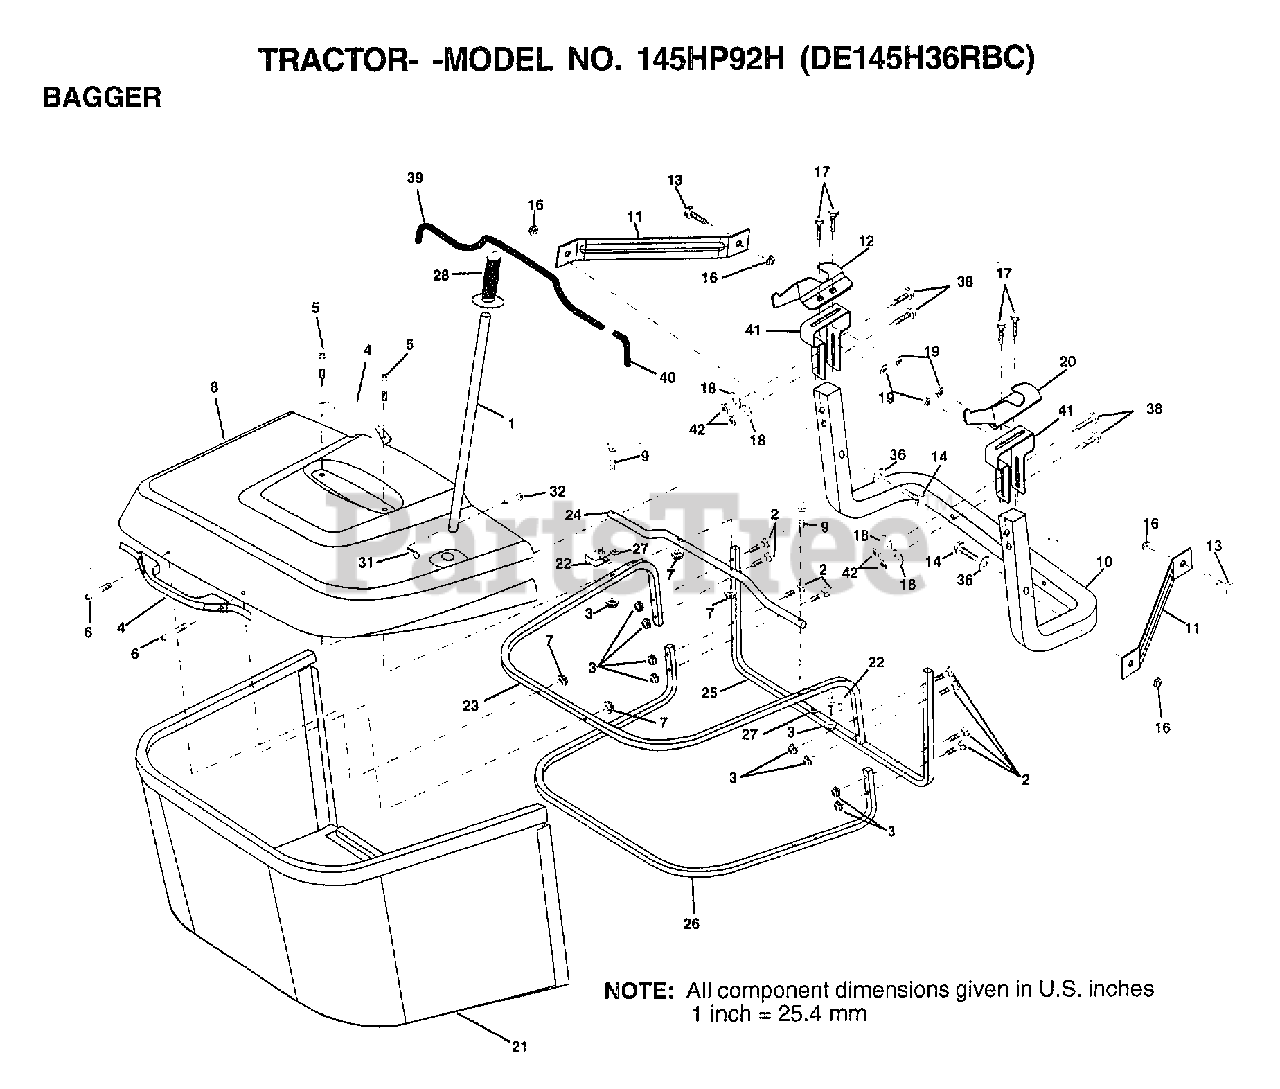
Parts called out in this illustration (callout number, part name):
1	TUBE HANDLE BAGGER
2	BOLT.CARRIAGE.1/4-20X2.0
4	HANDLE BAGGER
5	"SCREW,PAN.HEAD"
7	NUT.WIZ.LOCK
8	COVER.BAGGER.CRD
9	BOLT CARRIAGE
10	TUBE SUPPORT BAGGER CRD
11	BRKT.SUPT.UPPER.BAG.CRD
12	BRACKET HORIZ ADJ BGGR LH CRD
13	BOLT
14	BOLT.HEX.3/8-16X2-1/2
17	BOLT
18	WASHER M
19	"NUT HEX,LOCK,FLAN"
20	BRACKET HORIZ ADJ BGGR RH CRD
21	BAG.ASM.CRD
22	BRKT.SIDE.BAG.CRD
23	TUBE.UPPER.BAG.CRD
24	TUBE.PIVOT.BAG.CRD
25	TUBE.FT.BAG.CRD
26	TUBE.LOWER.BAG.CRD.
27	BUSHING SNAP BAGGER CRD
28	GRIP
31	RETAINER M
32	RIVET.DRILL.1.75
38	BOLT.5/16-18X2.5
41	BRACKET VERT ADJ BAGGER CRD
42	NUT
